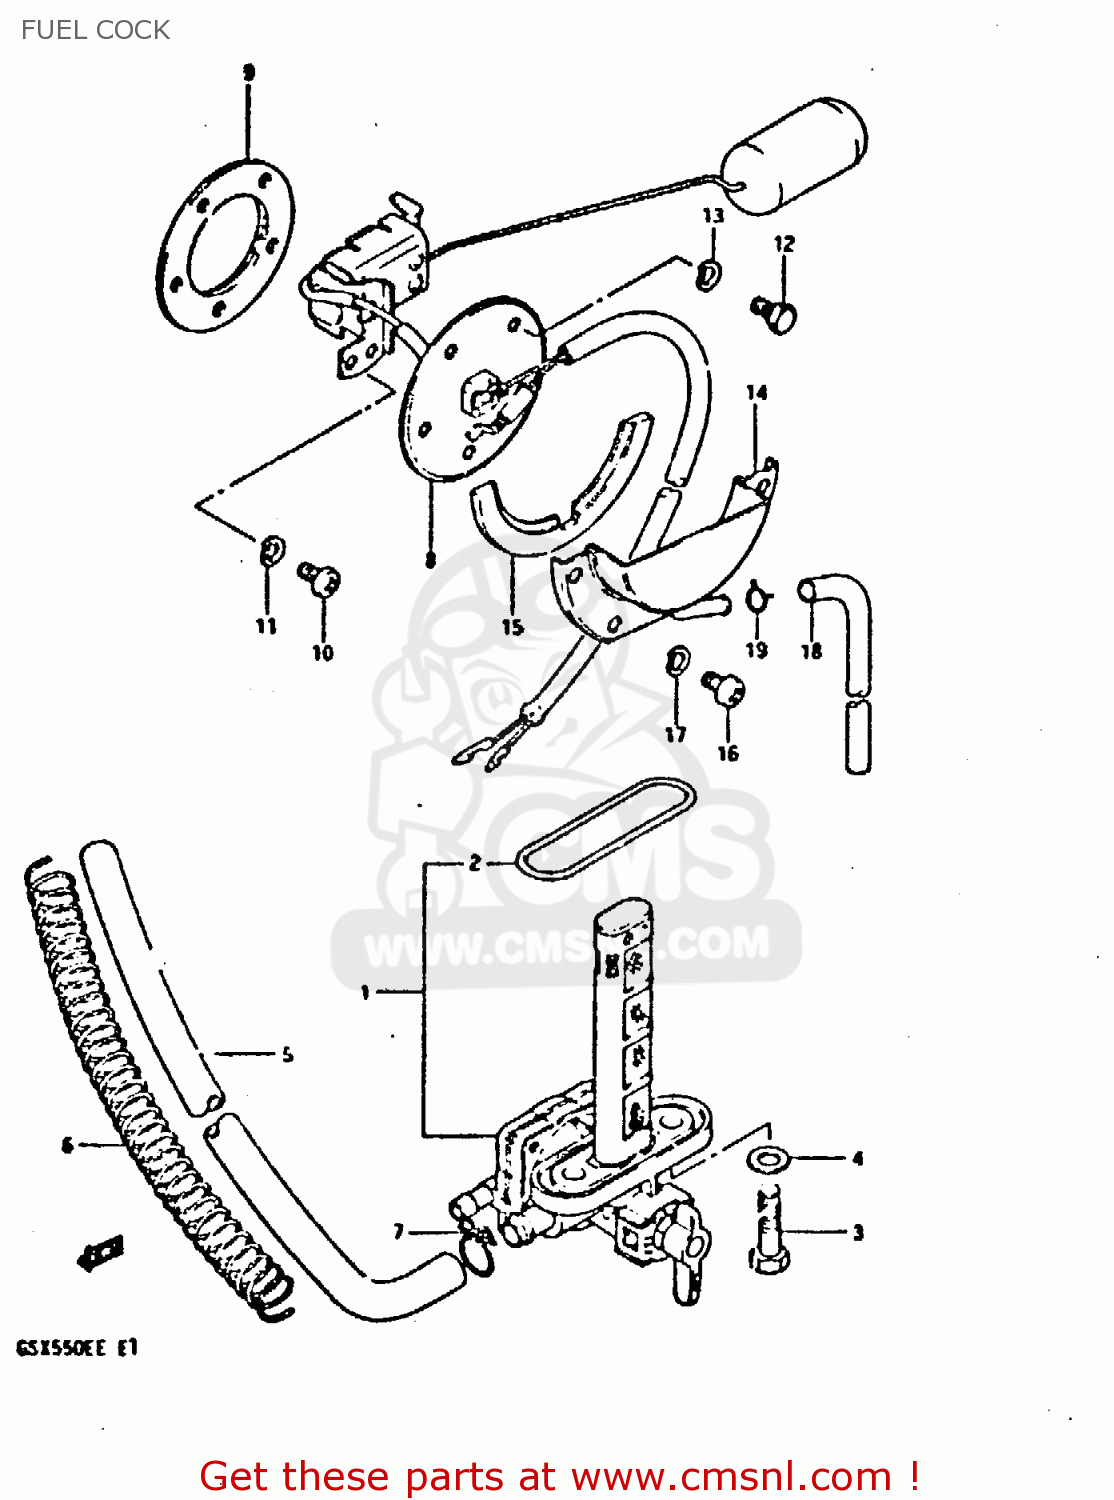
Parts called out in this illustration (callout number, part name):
1	COCK ASSEMBLY,FUEL
2	O RING
3	BOLT(6X20)
4	GASKET
5	HOSE
6	SPRING
7	CLIP
8	GAUGE ASSEMBLY,FUEL LEVEL
9	GASKET,FUEL LEVEL GAUGE (NAS)
10	SCREW 5X10
11	LOCK WASHER
12	BOLT 5X10
13	LOCK WASHER
14	PLATE,FUEL DRAIN
15	GASKET (NAS)
16	SCREW
17	LOCK WASHER
18	HOSE,FUEL
19	CLIP
